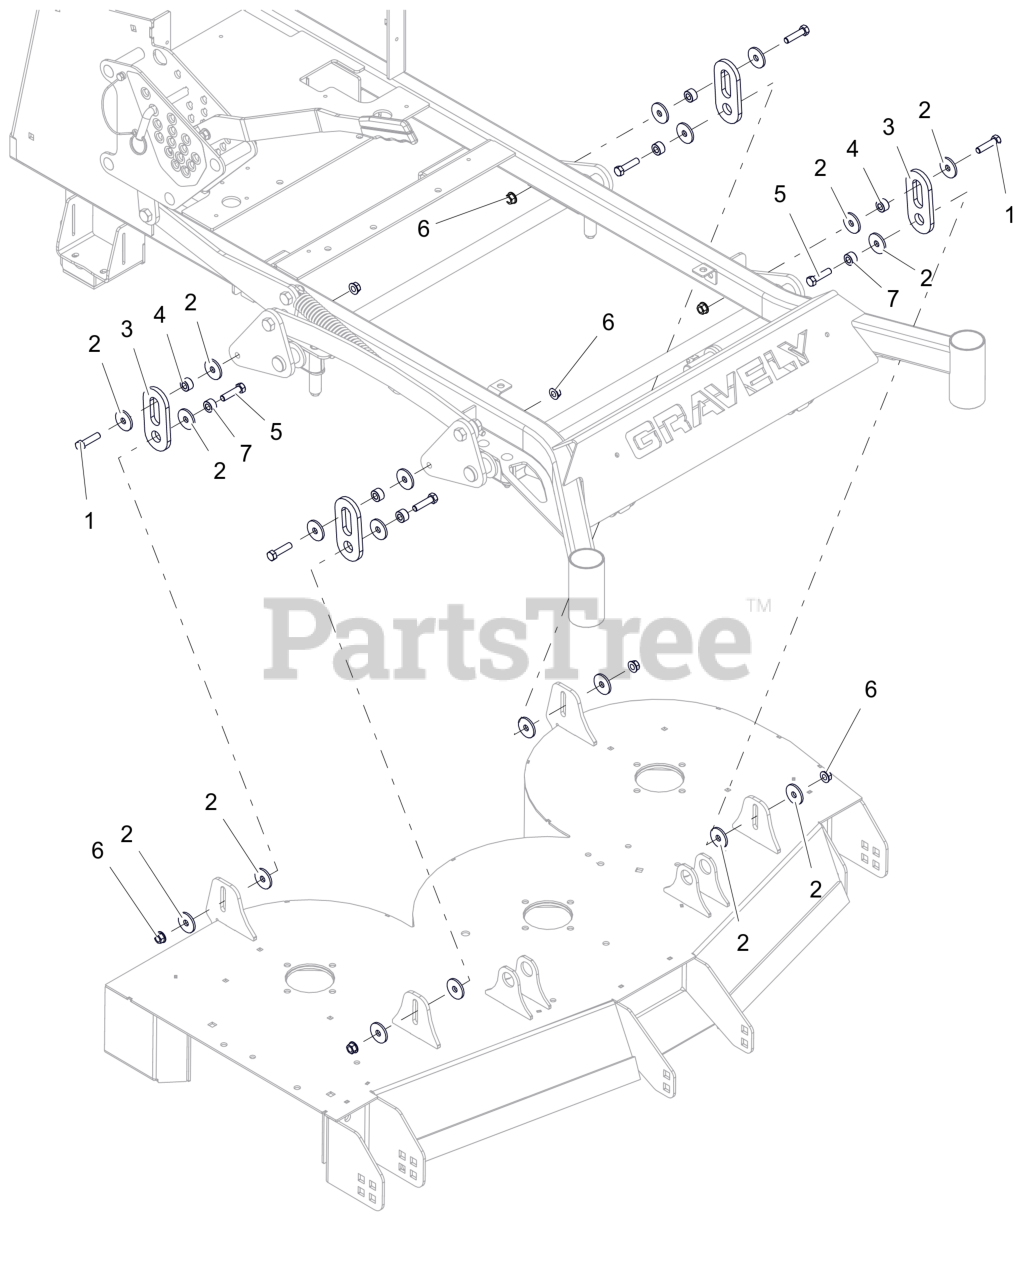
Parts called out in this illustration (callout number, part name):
1	BLT, HEX .38-16X1.50 G5 ZCC
2	WSHR,FLT .406X1.375X.135 ZCC
3	PLATE- DECK HANGER (BLACK)
4	SPCR- .390 X .750 X .438
5	BLT, HEX .38-16X1.50 G5 ZCC
6	NUT-LK-CTR-FLG .375-16 GF ZCC
7	SPCR- .390 X .750 X .438
